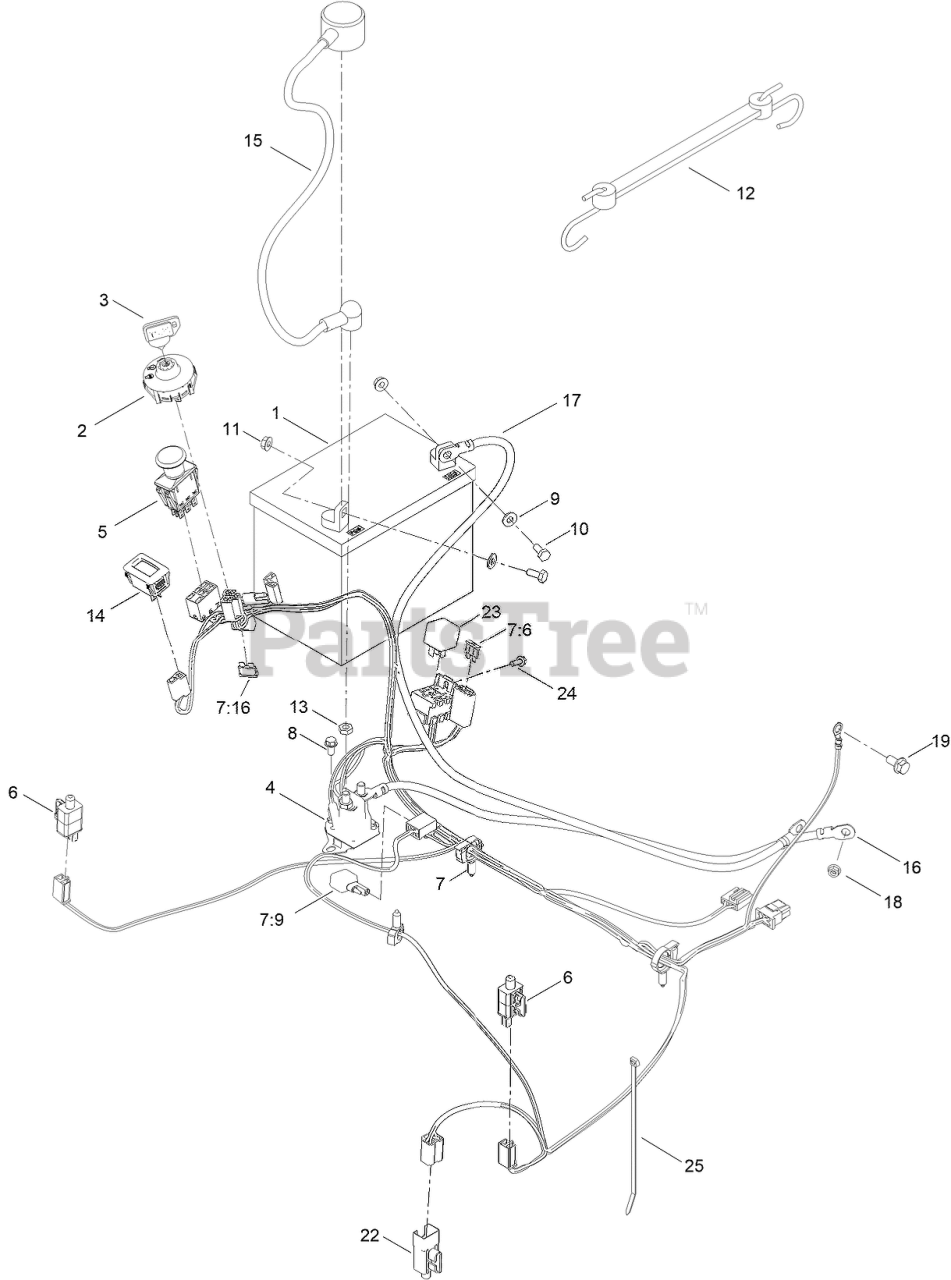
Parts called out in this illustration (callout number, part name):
1	BATTERY-DRY
2	SWITCH-IGNITION
3	KEY-IGNITION
4	SOLENOID
5	SWITCH-PTO
6	SWITCH
7	HARNESS-WIRE
7:6	FUSE-BLADE, 25 AMP
7:16	FUSE-BLADE, 15 AMP
8	SCREW-HWH
9	WASHER-FLAT
10	SCREW-HH
11	NUT-HF
12	HOLDDOWN-BATTERY
13	NUT-JAM
14	HOURMETER
15	CABLE-BATTERY, POSITIVE
16	CABLE-BATTERY, RD ASM
17	CABLE-BATTERY, NEGATIVE
18	NUT-HF
19	SCREW-HHF
22	SWITCH-REVERSE
23	RELAY
24	SCREW-TAPTITE
25	TIE-CABLE
